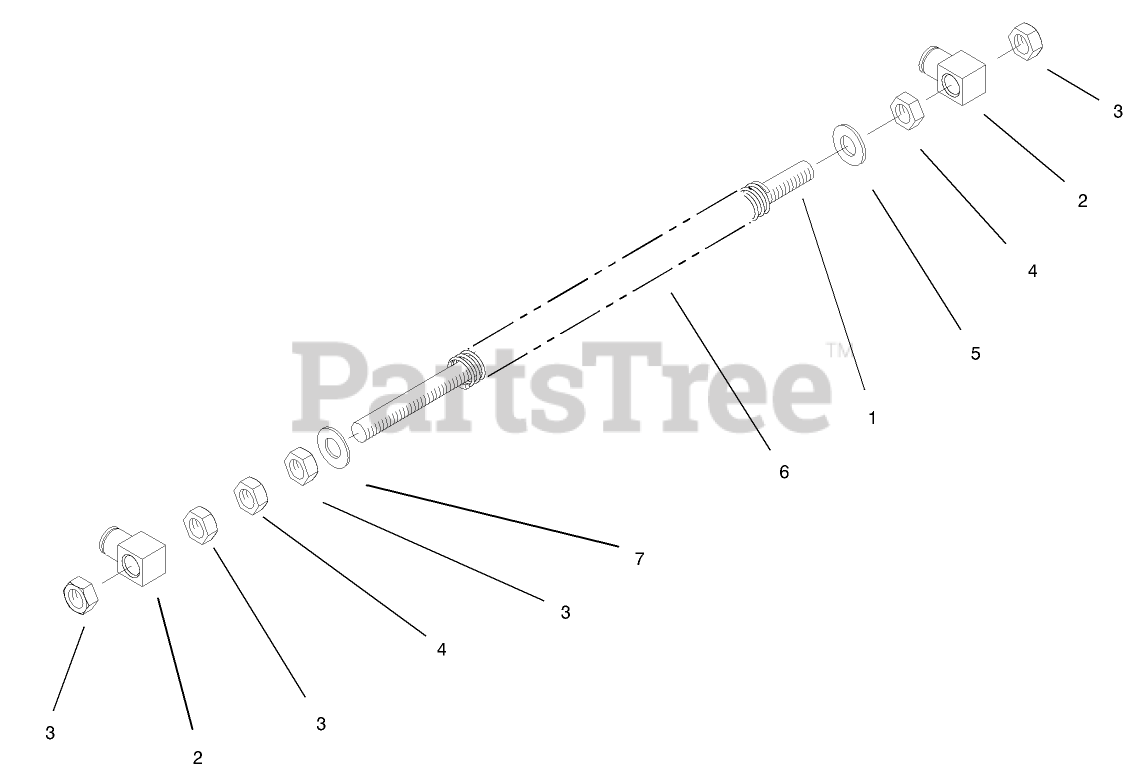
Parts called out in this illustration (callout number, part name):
1	ROD-LIFT, DECK
2	SWIVEL-DECK MOUNT, REAR
3	NUT-HEX
4	NUT-JAM
5	Washer
6	SPRING-COMPRESSION
7	WASHER-FLAT
